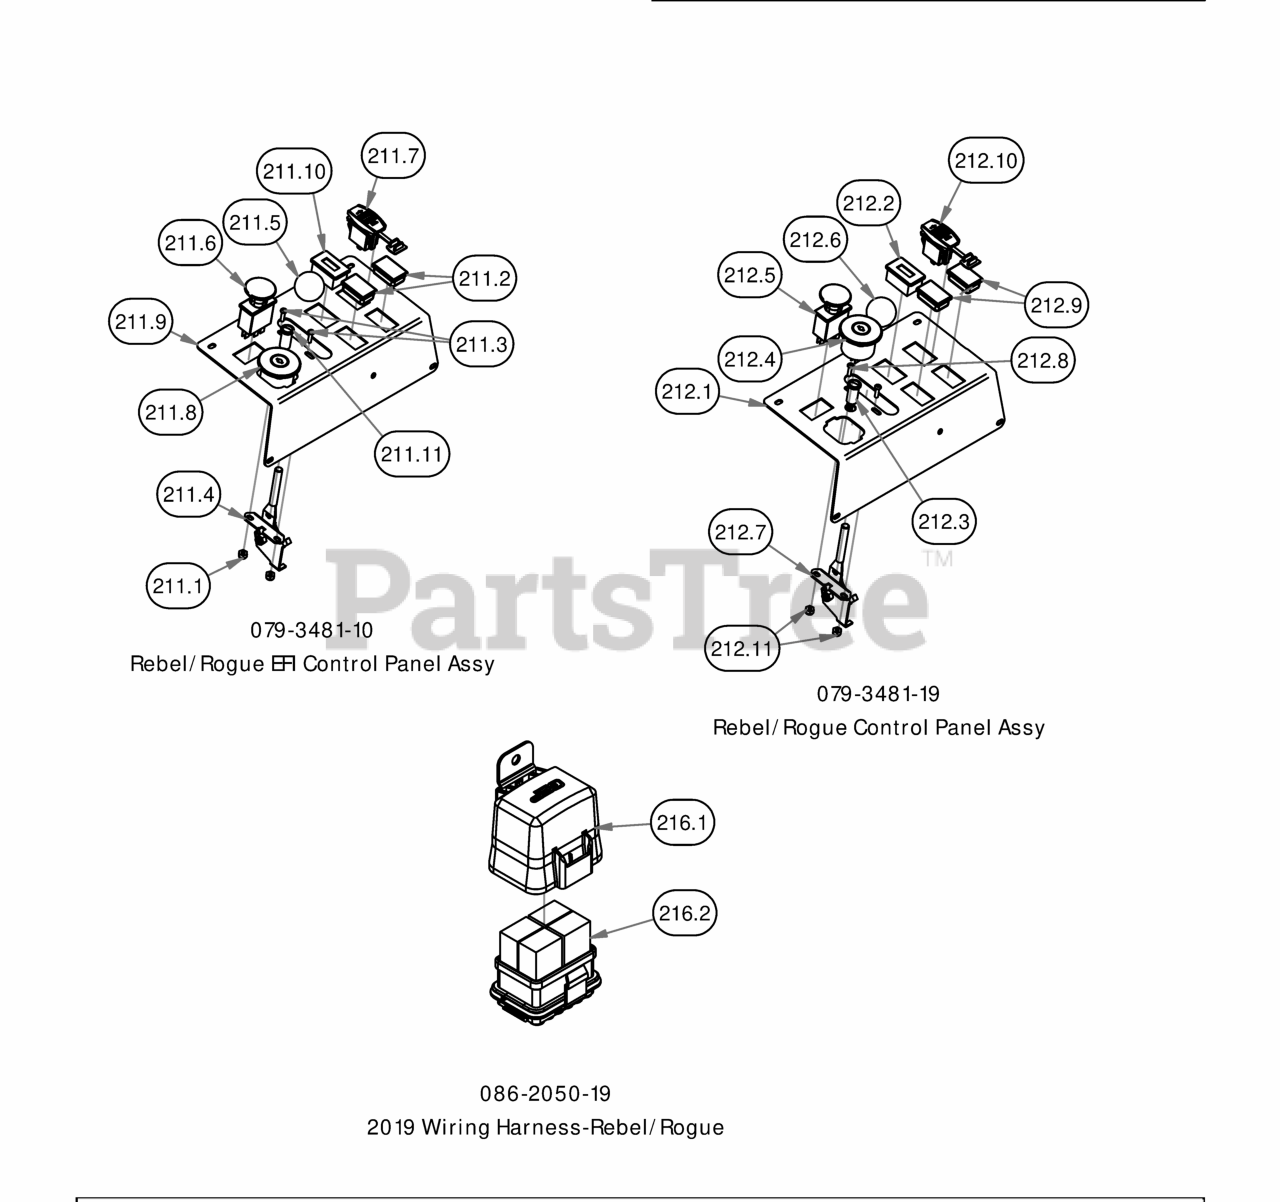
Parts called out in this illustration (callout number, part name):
211.1	10-24 Nylon Insert Locknut Zinc Orange Nylon
211.2	Light Plug
211.3	10-24 X 5/8 BS Button Head Bolt
211.4	Universal Throttle
211.5	Throttle Knob
211.6	PTO Switch
211.8	Ignition Switch
211.9	2019 Outlaw Control Panel
211.10	Tachometer
212.1	2019 Outlaw Control Panel
212.2	Tachometer
212.4	Ignition Switch
212.5	PTO Switch
212.6	Throttle Knob
212.7	Universal Throttle
212.8	10-24 X 5/8 BS Button Head Bolt
212.9	Light Plug
212.11	10-24 Nylon Insert Locknut Zinc Orange Nylon
216.1	Relay Block Cover Replacement Kit
